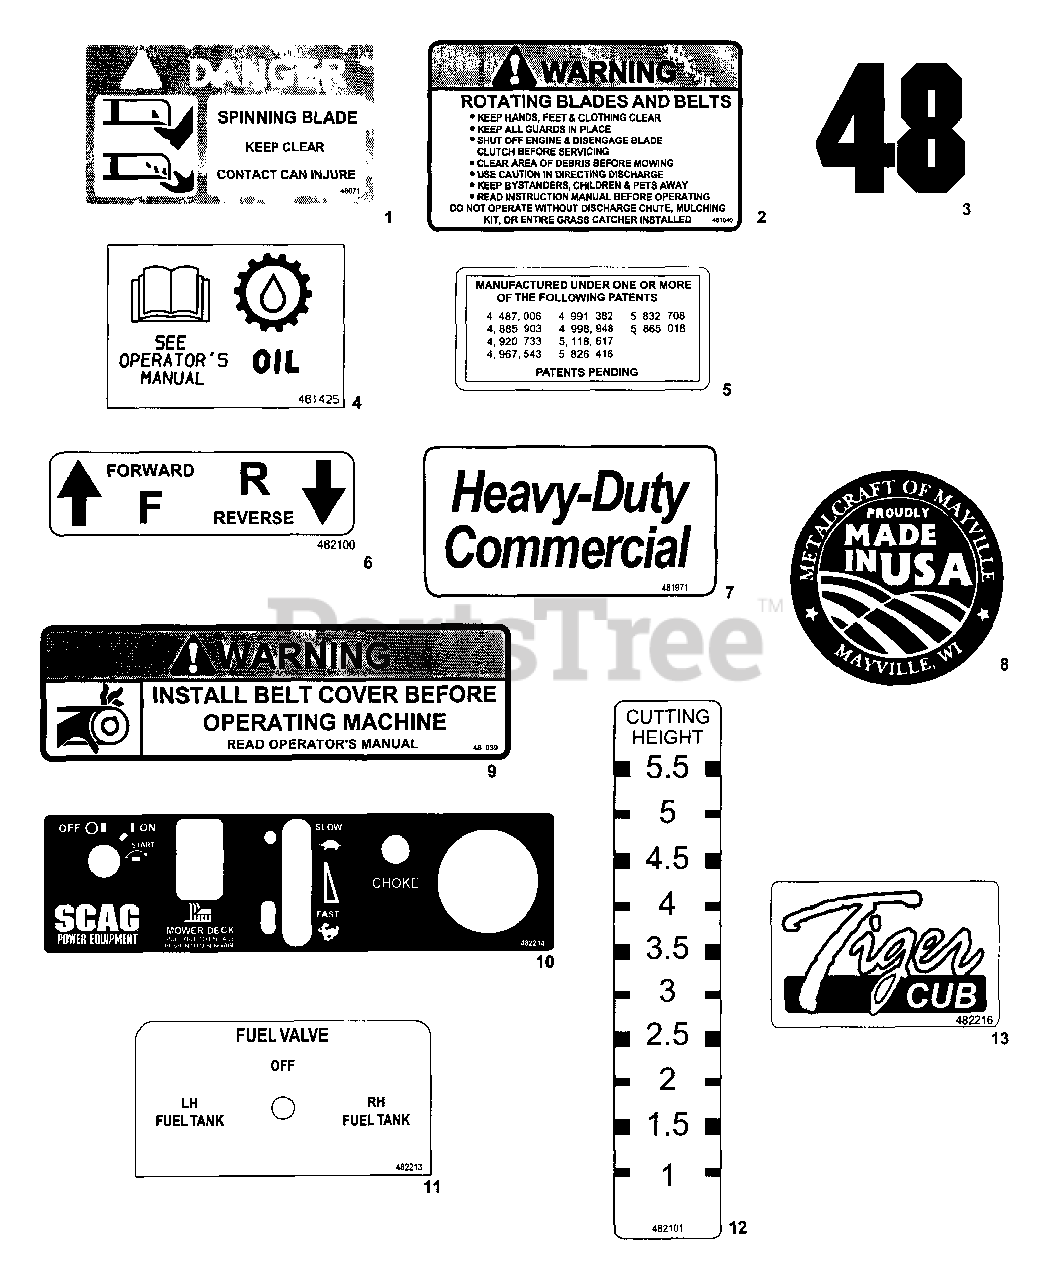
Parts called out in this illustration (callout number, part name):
1	Decal, Danger-Spinning Blades
2	Decal, Warning-Rotating Blades
3	Decal, 40
4	Decal, Oil
5	Decal, Patents
6	Decal, Traction Control
7	Decal, Heavy Duty Commercial
8	Decal, Metalcraft - Made in USA
9	Decal, Belt Cover
10	Decal, instrument Panel
11	Decal, Fuel Valve Position
12	Decal, Cutting Height
13	Decal, Control Panel
